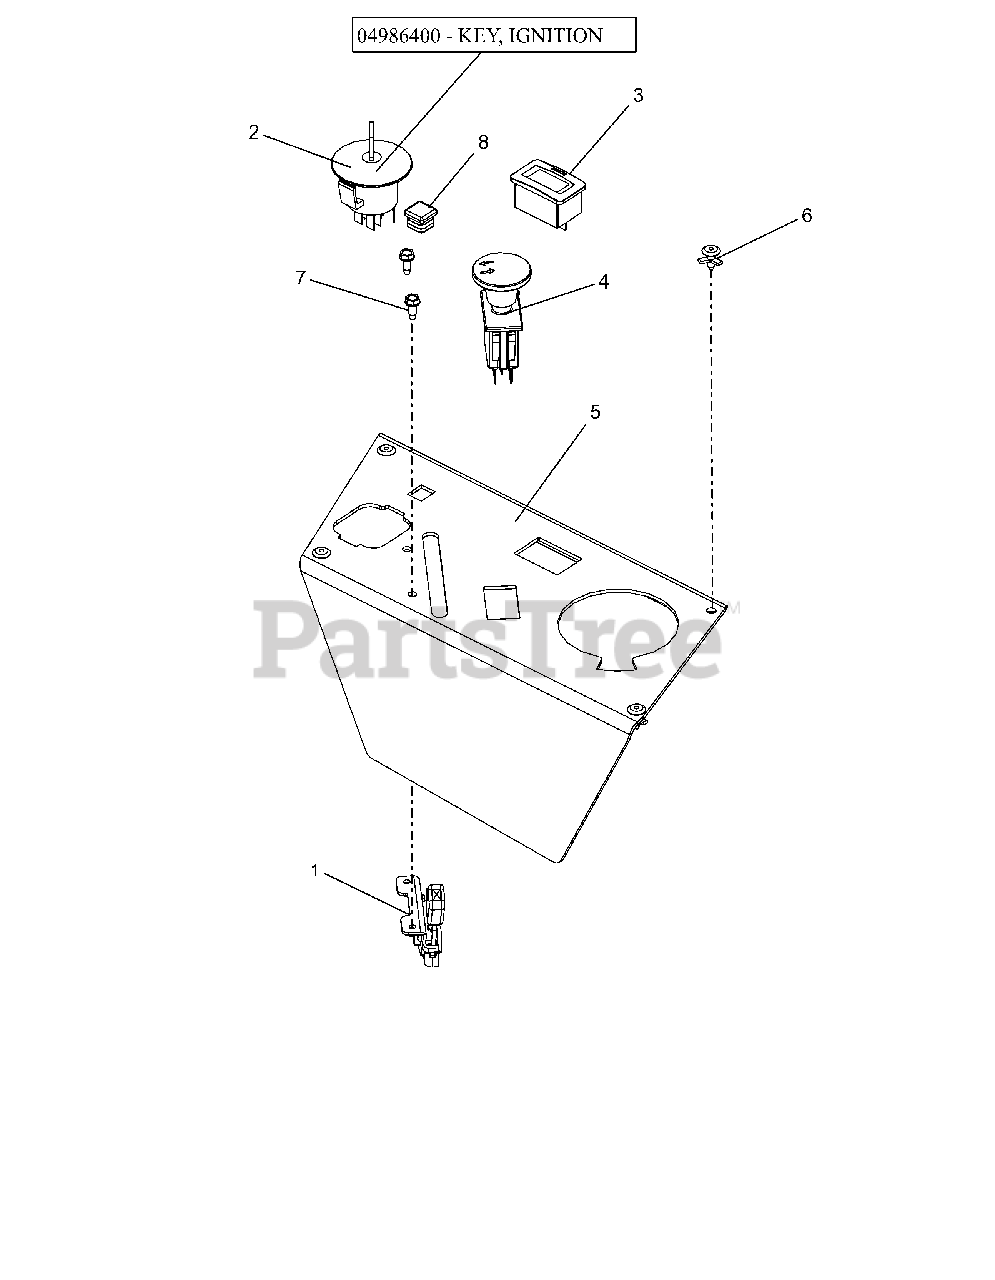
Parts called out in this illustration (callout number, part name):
1	CABLE - THROTTLE CONTROL
2	KEYSWITCH-IGNITION 4 POS
2	KEY, IGNITION
3	HOUR METER
4	SWITCH, CLUTCH (YELLOW)
5	PANEL, CONTROL
6	RIVET, PLASTIC .195 DIA.
7	@SCR-TAP 10-24X.50 HWH TR YWZC
8	PLUG, 5/8" SQ BLACK (14-20GA)
